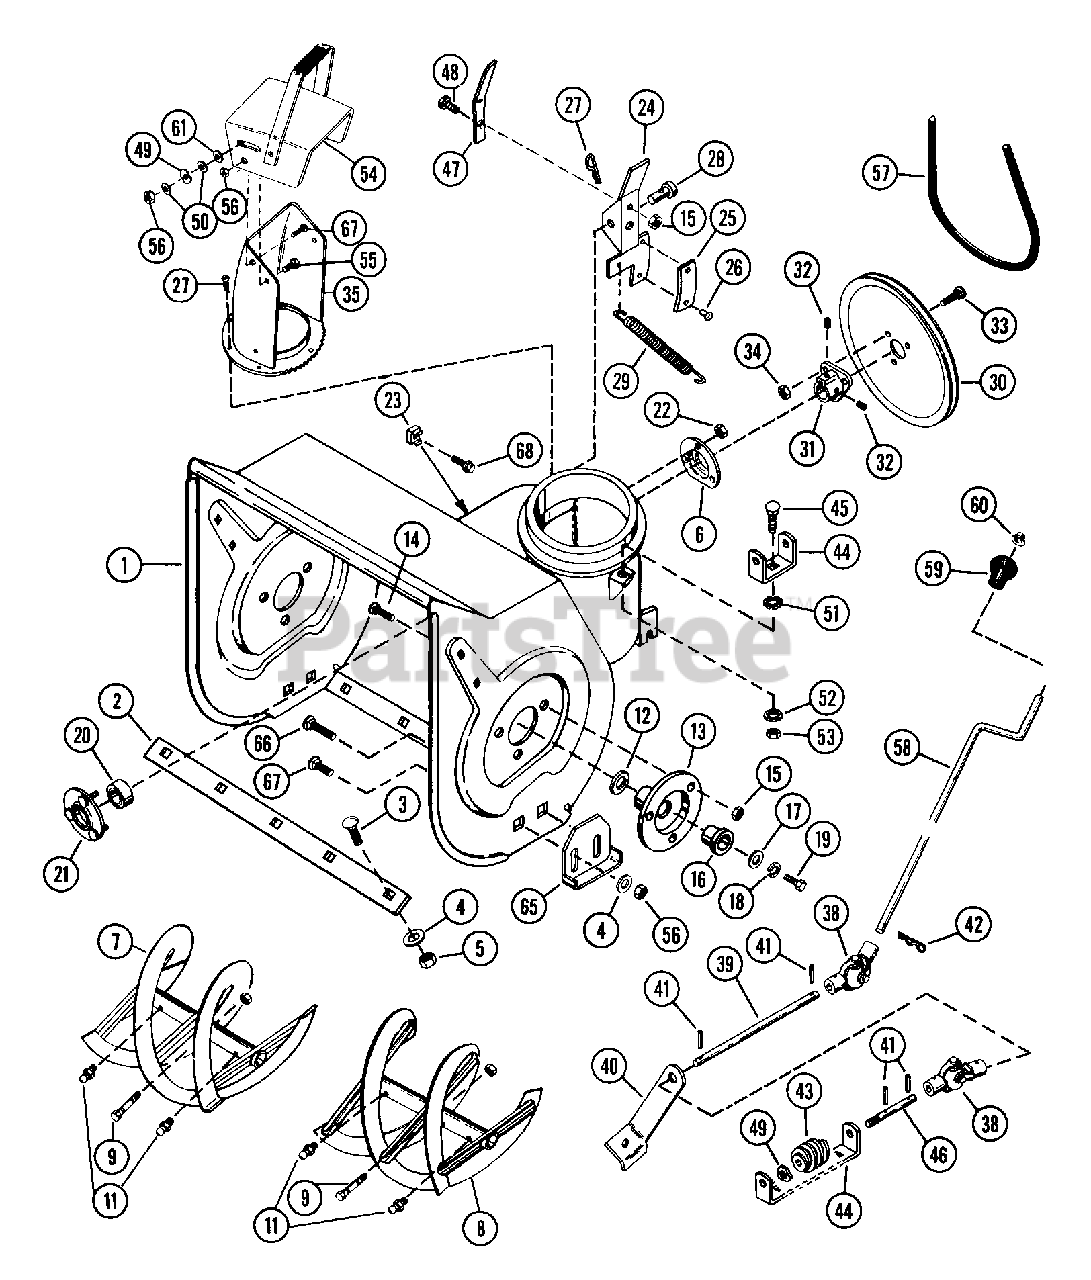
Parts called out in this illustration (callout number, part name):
1	BLOWER HOUSING W/DECALS 32
2	SCRAPER BLADE 32"
3	BLT-RDHDSQNK .312-18X.62 PL
4	WSHR-FL-STL .38X.875X.083 PL
5	NUT-LK .312-18 GR A PL
6	BEARING FLANGE
7	RAKE, RIGHT-32"(1ID X 15.75OD)
8	RAKE, LEFT-32"(1"ID X 15.75OD)
9	SHEAR BOLT SERVICE ASSEMBLY
11	SPIN DRIVE ZERK FITTING
12	WSHR-FL-STL 1.010X1.505X.062PL
13	BEARING SUPPORT
14	BLT-SERNK SL .25-20X.50 PL
15	NUT-LK-FLG .250-20 PL
16	BSHG-FLG 1.000X1.12X.62X1.50BR
17	WSHR-FL-STL .511X1.441X.125 PL
18	WSHR-LK .500X.151 HVY PL
19	BLT-HEX .50-13X1.00 PL GR2
20	BRG-BALL 1.0X2.0X.56
21	BEARING FLANGE
22	NUT-LK-CTR .250-20 PL
23	NUT-RETNR .38-16 TINRMAN
24	BRAKE ARM ASSEMBLY
25	BRAKE LINING
26	RVT-TBLR .187X.437 RH ST PL
27	PIN-HAIR INT .06X.18X.77
28	PIN-CLEV .371X1.16 YWZC
29	SG-TENS .062X.56X8.0 WLD 11
30	PLY-V 9.0 X 1.25 3BLT
32	SCR-SET .32-18X.38 SKHCUPNL OH
33	BLT-SERRDHD SL .31-18X.87 PL
34	NUT-FLG. .312-18 PL
35	DISCHARGE CHUTE
36	CHUTE CLAMP
37	SCR-TAP 10-24X.375 HWH PL TR
38	UNIVERSAL JOINT ASSY
40	CHUTE CRANK BRACKET
41	PIN-ROLL .125X.75
42	PIN-HAIR INT .08X.38X1.42 YWZC
43	WORM GEAR L.H.
44	WORM CLEVIS
45	BLT-RDHDSQNK .31-18X.75 GR5 PL
46	WORM SHAFT
48	BLT-HEX .25-20X.50 PL GR2
49	WAVE WASHER .390X.655X.110
50	WSHR-FL-STL.406X.812X.065PL
51	WSHR-LK-EXT .375X.035 PL
52	WSHR-LK .313X.062
53	NUT-HEX .312-18
54	DEFLECTOR W/ DECAL
55	BLT-HEX .38-16X.75 PL GR2
56	NUT-LK-CTR .375-16 GR A PL
57	V-BELT, 4L-RAW EDGE
58	CHUTE CONTROL CRANK
60	CAP, 3/8 ROD YWZC
61	WSHR-PLASTIC .390X.875X.062
65	RUNNER - SKID SHOE
66	BLT-RDHDSQSHNK .38-16X1.00 PL
67	BLT-RDHDSQNK .38-16X.75 SHT PL
68	BLT-SCRHFWH .38-16X.75 PL
